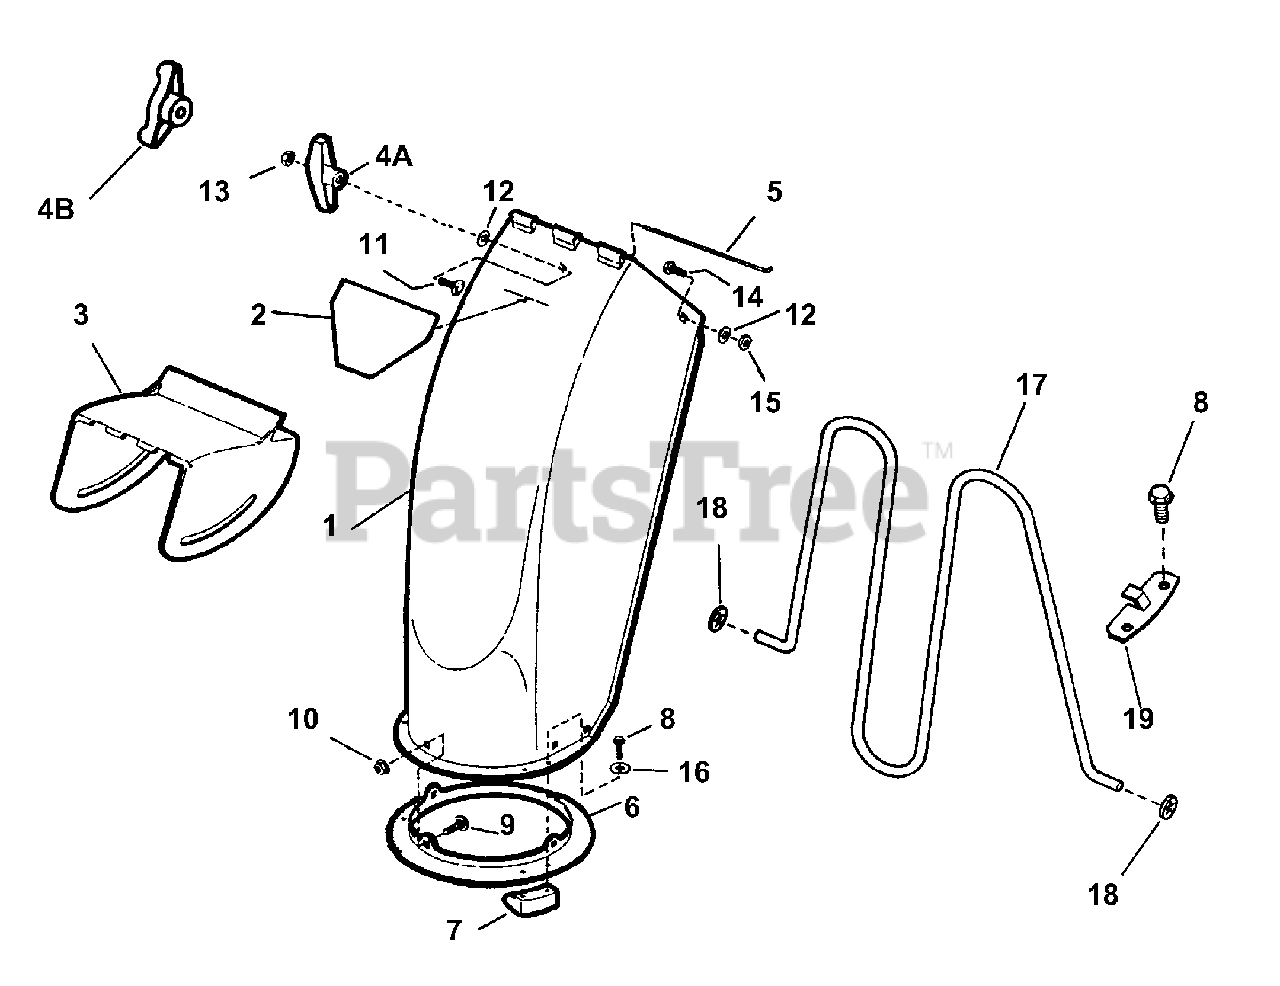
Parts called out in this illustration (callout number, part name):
1	ASSEMBLY, Discharge Chute
2	DECAL, Danger
3	DEFLECTOR, Discharge Chute
4A	T-KNOB (Plastic)
4B	T-KNOB (w/5/16-18 insert)
5	PIN, Hinge
6	RING, Chute
7	RETAINER (Chute Ring to Housing)
8	SCREW, #10-24 x 5/8" Hex Washer Self-Tapping
9	BOLT, 5/16-18 x 5/8" Square Neck Carriage, Grade 5
10	NUT, 5/16-18 Hex Flange Lock, Grade 5
11	BOLT, 5/16-18 x 3/4" Square Neck Carriage, Grade 5
12	WASHER, 5/16 Flat
13	NUT, 5/16-18 Hex, Grade B or 5
14	SCREW, 5/16-24 x 3/4" Hex Head Cap, Grade 5
15	NUT, 5/16-24 Hex Center Lock, Grade B
16	WASHER, 7/32 Flat
17	WIRE, Safety (Euro)
18	PUSH-ON Fastener, .5/32" Dia. (Euro)
19	RETAINER, Safety Wire (Euro)
